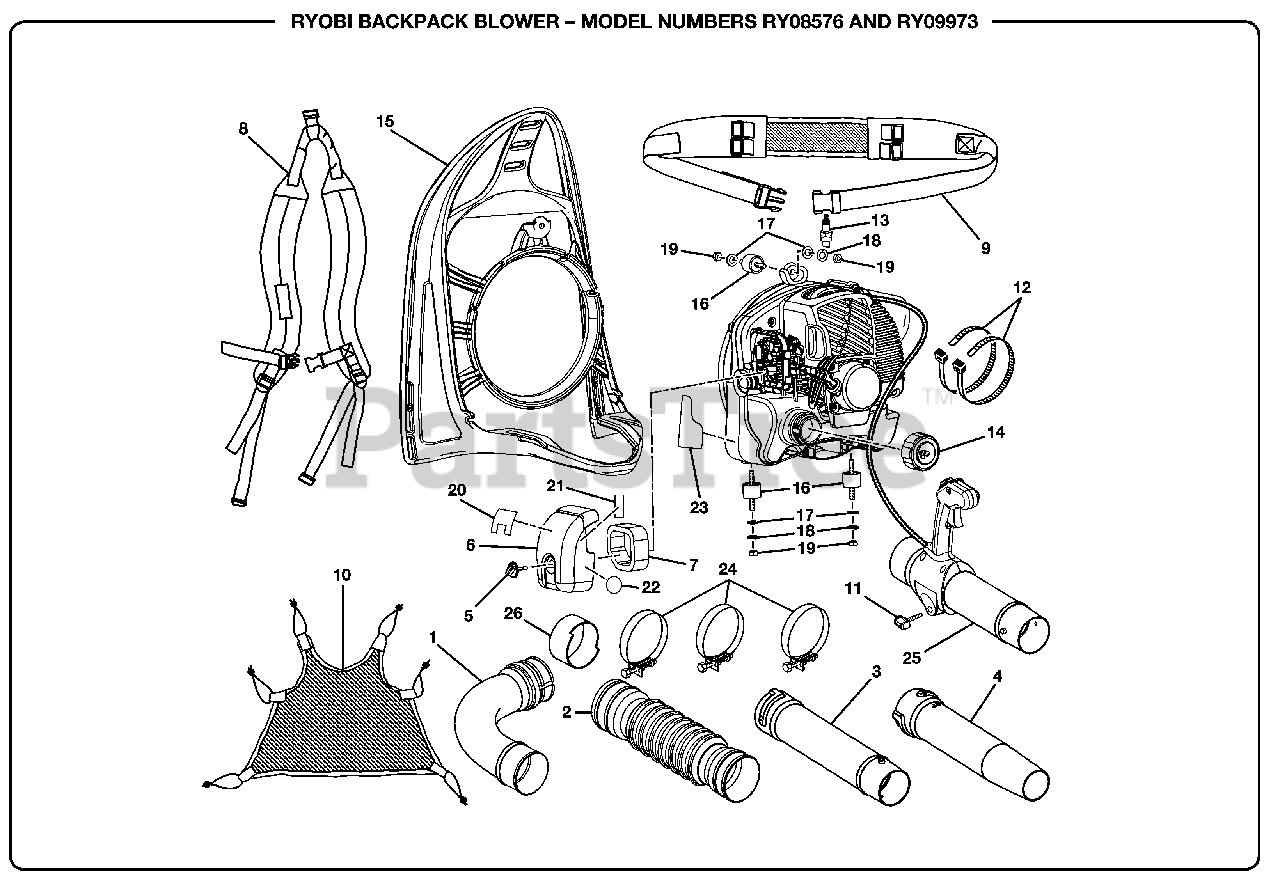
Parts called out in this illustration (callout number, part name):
1	Elbow Tube
3	Straight Tube (Upper Tube)
4	Nozzle (Lower Tube)
5	Air Filter Knob
6	Air Filter Cover
7	Air Filter
8	Shoulder Harness Assembly
9	Waist Harness
10	Mesh Backing
11	Throttle Control Handle Screw
12	Cable Tie
13	Spark Plug
14	Fuel Cap Assembly
15	Backpack Frame
16	Vibration Isolators
17	Flat Washer
18	Spring Washer
19	Hex Nut (1/4 - 20)
20	Starting Instructions Label
21	Starting Label
22	Zip Start Label
23	Warning Label
24	Tube Clamp
25	Throttle Control Handle Tube
